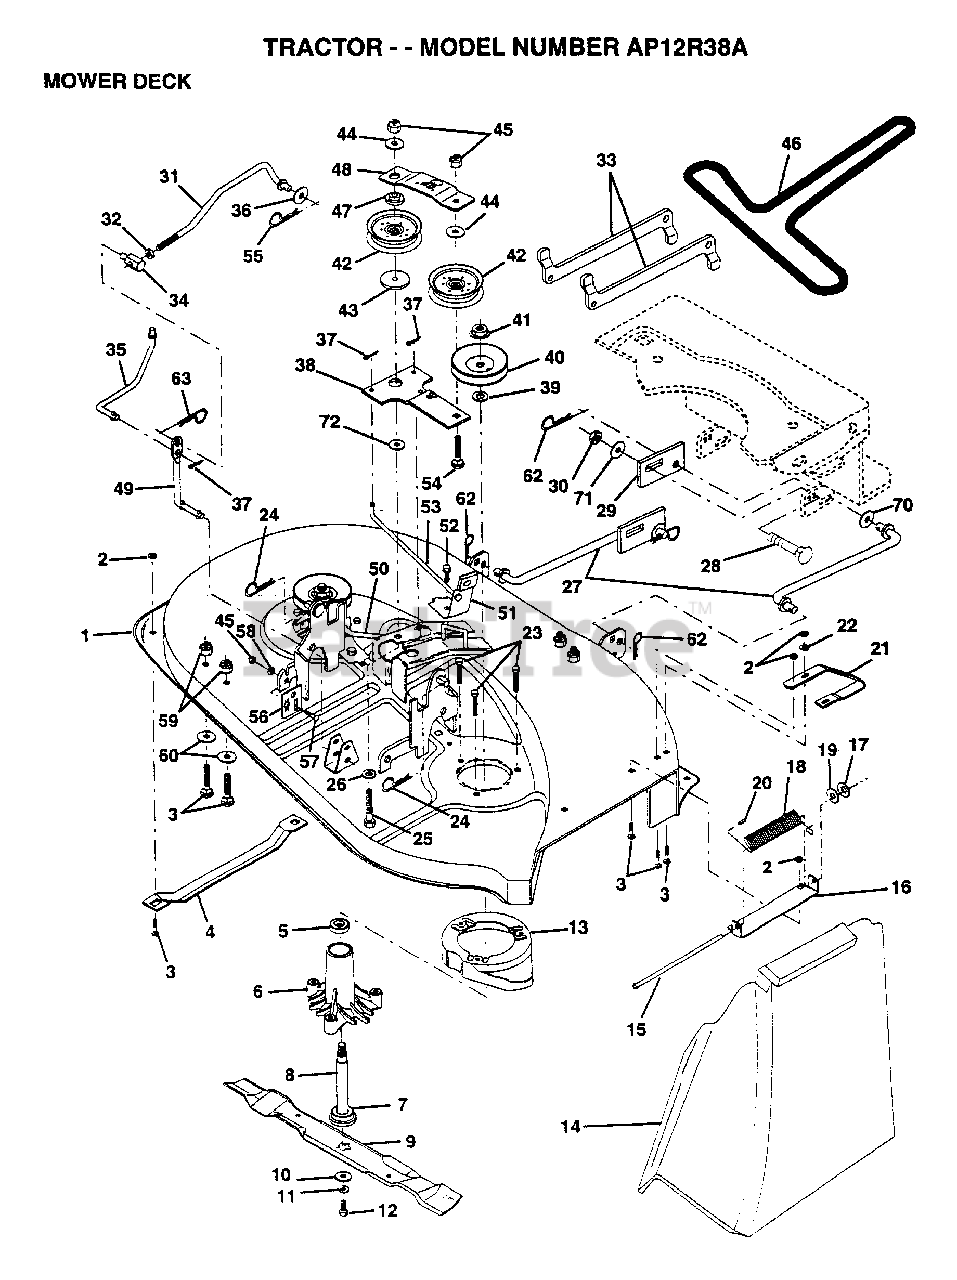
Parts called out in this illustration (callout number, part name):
1	MOWER.WELD.LR.38
3	BOLT
4	RUNNER-LH M
5	BEARING
6	HSG ASM MANDREL
7	BEARING.BALL
9	"BLADE.38"" HIPERF"
10	WASHER.HARD.BLADE
12	BLADE BOLT
13	STRIPPER RND MWR
14	DEFLECTOR-SHLD T
15	ROD-HINGE T
16	BRKT DEFLECTOR
17	NUT PUSH M
18	SPRING TORSION
19	WASHER
20	CAP-SLEEVE LT
21	RUNNER RH
22	WASHER M
25	BOLT
26	WASHER GT
27	"LINK LIFT 38"""
29	PLATE SLIDE LINK
30	NUT
31	ROD.CLUTCH.PRIM
32	NUT
33	SUSP ARM REAR
34	TRUNNION
35	CLUTCH ROD SEC
36	WASHER
38	IDLER ARM ASSY
39	WASHER
42	PULLEY IDLER
43	SPACER RETAINER
44	WASHER GT
46	V BELT
47	RETAINER SPACER
48	IDLER ARM STIFF
49	PIVOT ROD
50	BRAKE ROD LH
51	BRAKE ASM
52	SCREW
53	BRAKE ROD RH
54	BOLT
55	SPRING.RETAINER
56	PLATE ADJ LINK LH
58	WASHER T
60	WASHER.34X.68X16
61	BOLT
62	RETAINER.SPRING
63	RETAINER M
70	WASHER 1/2X1 1/4
71	WASHER PM
72	HARDENED WASHER
